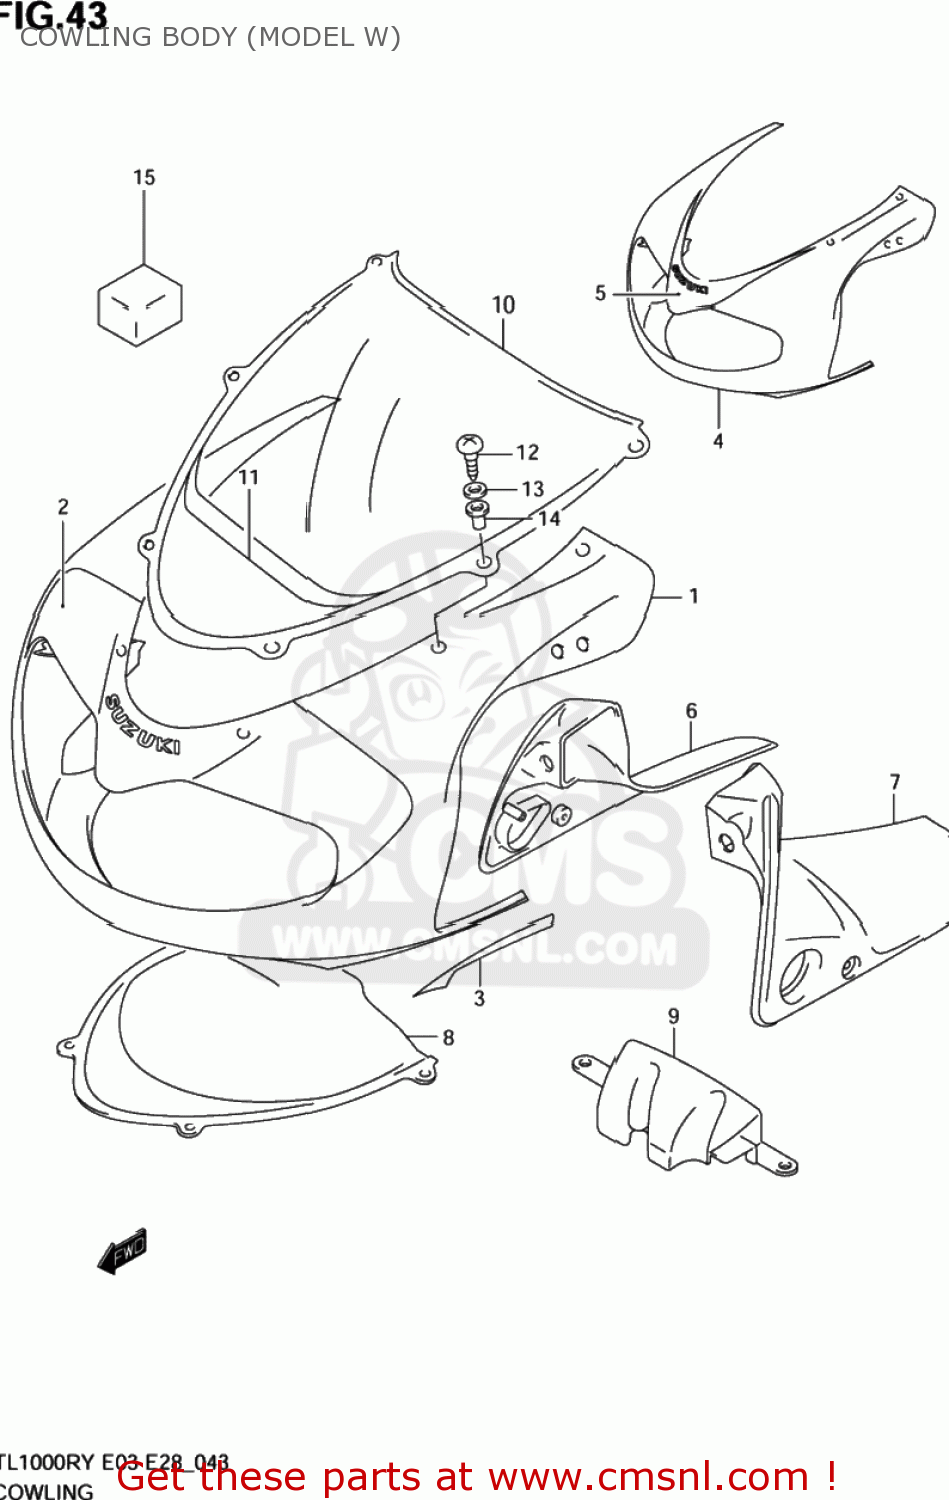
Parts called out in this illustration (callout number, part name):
1	COWLING ASSY,BODY(BLUE)
2	TAPE SET,BODY FR
3	TAPE SET,BODY SIDE(WHITE)
4	COWLING ASSY,BODY(YELLOW)
5	TAPE SET,BODY FR
6	PANEL,SIDE,R(BLACK)
7	PANEL,SIDE,L(BLACK)
8	COVER,BODY COWLING
9	COVER,COWLING FR LWR
10	WINDSCREEN
11	TAPE,WINDSCREEN
12	SCREW(5X14)
13	WASHER
14	NUT
15	CUSHION,BODY COWLING
